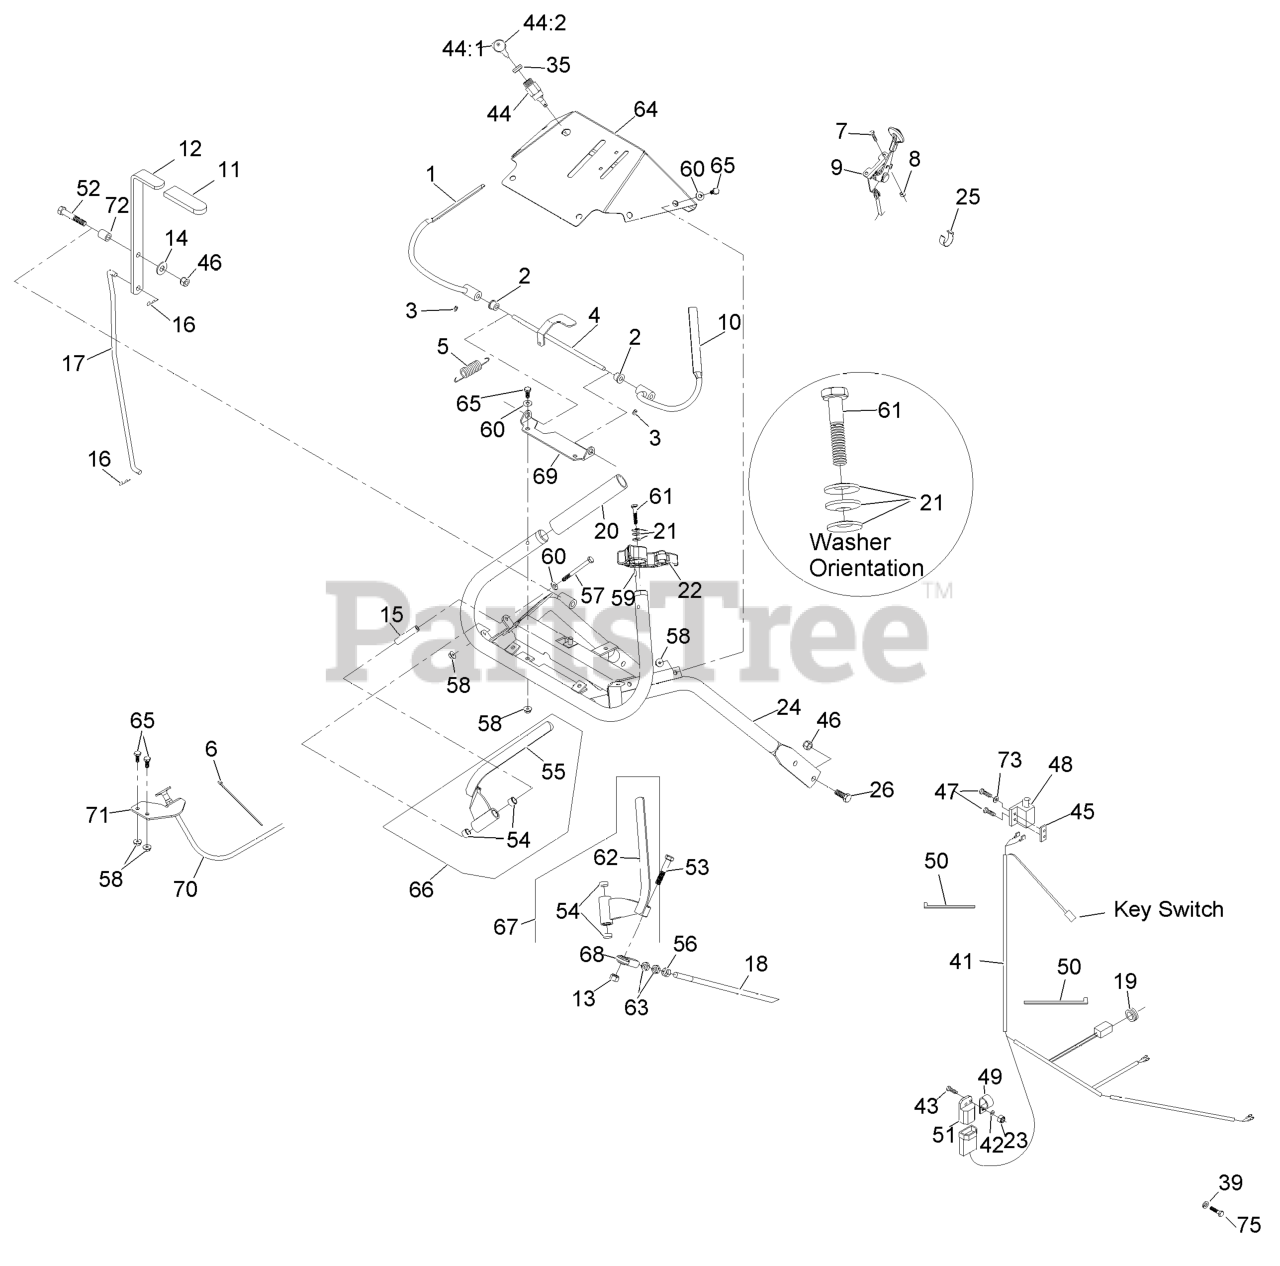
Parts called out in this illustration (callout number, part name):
1	WLD,LH OPC LEVER
2	BUSHING-NYLON
3	SCREW-SET
4	WLD,OPC LEVER AXLE
5	SPRING-EXTENSION
6	TIE-PLASTIC
7	BOLT-CARR
8	NUT-LOCK, NI
9	CONTROL, THROTTLE
10	WLD,RH OPC LEVER
11	GRIP-LEVER
12	CLUTCH LEVER-W/GRIP
13	NUT-LOCK, NI
14	WASHER-FLAT
15	BUSHING-LEVER, DRIVE
16	PIN-COTTER
17	LINKAGE,UPPER BLADE (PLT)
18	LINKAGE,DRIVE (PLT)
19	GROMMET
20	GRIP-BAR, HANDLE
21	WASHER-SPRING
22	ASM,RH THUMB LATCH
23	NUT-LOCK, NI
24	WLD,UPPER ECS HANDLE
25	CLIP-CABLE
26	SCREW-HH
35	NUT-SWITCH, IGNITION
39	WASHER-PLAIN
41	HARNESS-WIRE
42	WASHER-FLAT
43	SCREW-HH
44	SWITCH & KEY (INCLUDES NU
44:1	KEYS-IGNITION (SPARE PAIR
44:2	KEY-IGNITION
45	PLATE-TAPPED
46	NUT-LOCK, NI
47	SCREW-PPH
48	SWITCH-OPEN, NORMALLY
49	CLIP-LOOM
50	TIE-CABLE
51	MODULE-INTERLOCK
52	SCREW-CARR
53	SCREW-HH
54	BUSHING-SLEEVE
55	Lever, Drive (Lh)
56	NUT-HEX
57	SCREW-HH
60	WASHER-FLAT
61	SCREW-HH
62	Lever, Drive (Rh)
63	NUT-HJ
64	ASM, CONSOLE W/DECALS
65	SCREW-HH
66	DRIVE LEVER-ASM, RH
67	DRIVE LEVER-ASM, LH
68	JOINT-BALL, END
69	BRACKET,OPC AXLE
70	CABLE-CHOKE
71	BRACKET-CABLE, CHOKE
72	BUSHING-LEVER, LIFT
73	WASHER-FLAT
75	SCREW-HH
